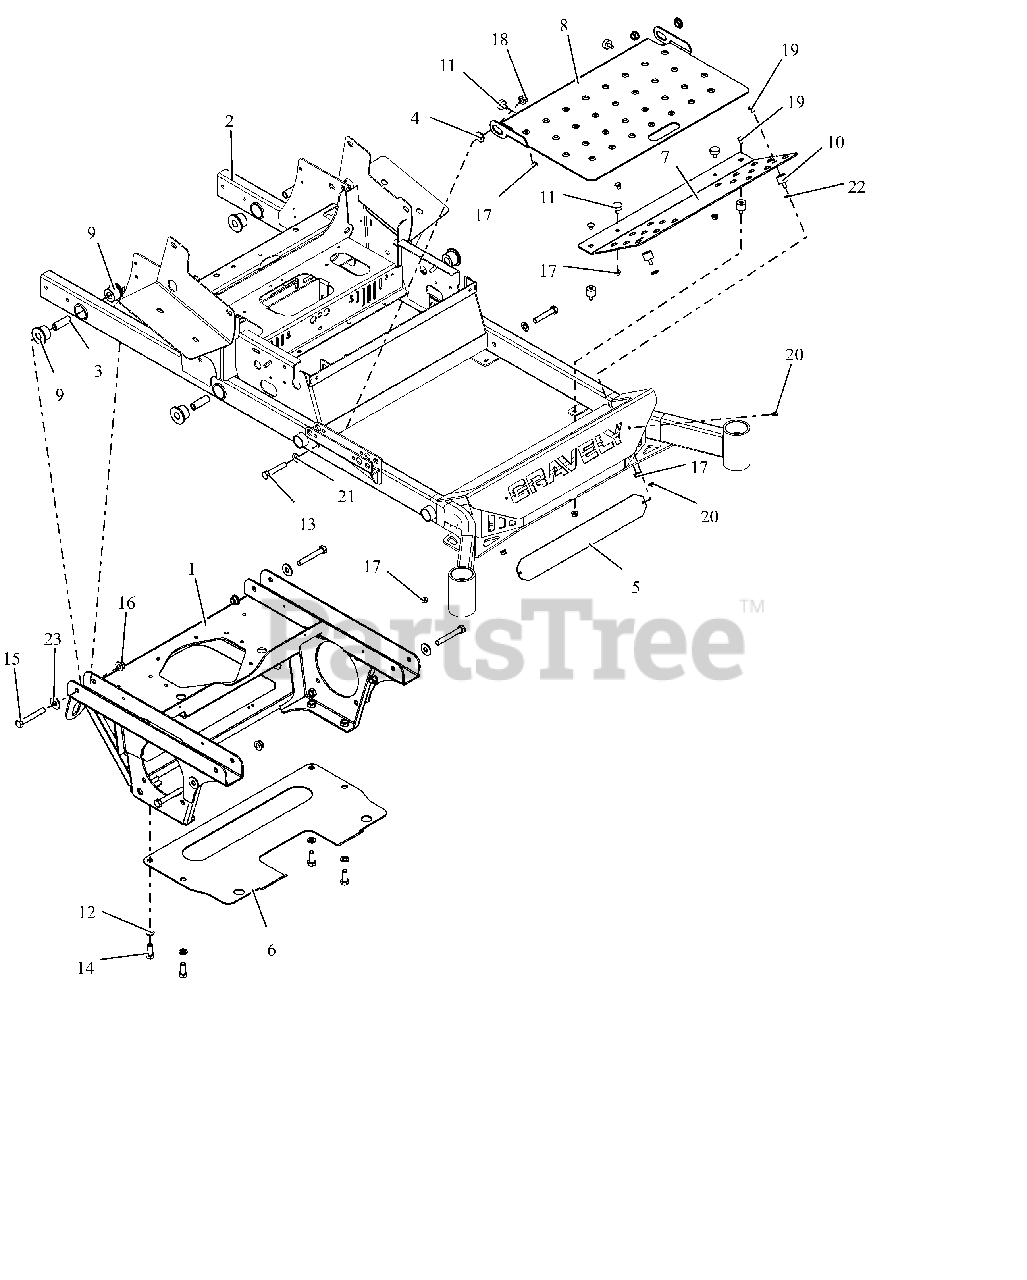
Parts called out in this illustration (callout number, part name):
1	PT200/400 AXLE/ENG FRM WMT-RED
2	52-60"PT200/400 FRAME W/DECALS
3	BSHG-SLV .50X.75X2.23
4	BSHG-FLG .515X.750X.310X1.120
5	BUMPER LOGO BACKING PLATE -BLK
6	PLATE-TRANSMISSION SKID
7	FOOTREST W/ SAFTEY DECALS
8	INSPECTION PANEL W/SAFE DECAL
9	BSHG-FLG .75X1.51X1.13X2.0 URE
10	BUMPER,STUD MNTD W/FEMALE INSR
11	BUMPER, RUBBER
12	WSHR,LK-REG .500X.125 ZCC
13	BLT,HEX .50-13X2.75 G5 ZCC
14	BLT,HEX .50-13X1.25 G5 ZCC
15	BLT, HEX .50-13X3.50 G5 ZCC
16	NUT,NYL-FLG .50-13 GF ZCC
17	NUT,SPNLK-FLG .31-18 G5 ZCC
18	NUT-LK-CTR-FLG .500-13 GG ZCC
19	BTL,RHSN .313-18 X 0.5 G5 ZCC
20	SCR-TAP .25-20X.50 HWH ZCC
21	WSHR, FLT .531X1.00X.063 ZCC
22	WSHR,FLT .375X.875X.083 ZCC
23	WSHR,FLT .563X1.375X.109 ZCC
